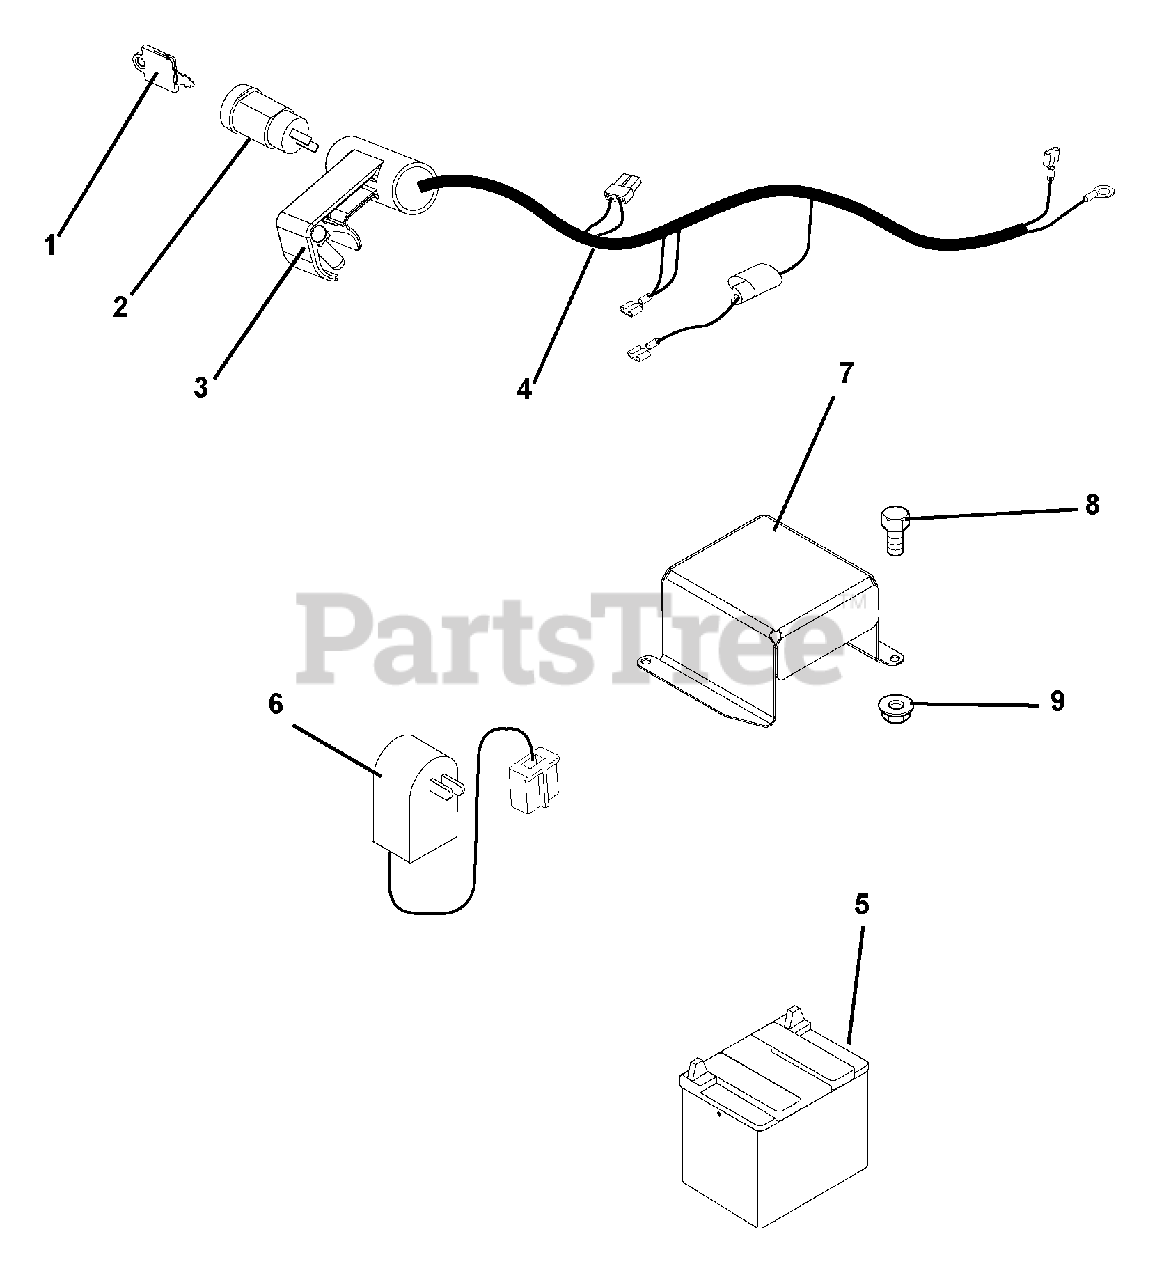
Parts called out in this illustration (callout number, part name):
1	KEY -W/CAP
2	KEYSWITCH
3	SNAP-ON E-START HOUSING
4	HARNESS, WIRE (WBLM)
5	BATTERY - 12V
6	CHARGER, BATTERY (WBLM)
7	COVER, BATTERY
8	@BLT-HEX 8-32 X .5 YWZC
9	@NUT-LK-NYL 8-32 W/INSTR YWZC
